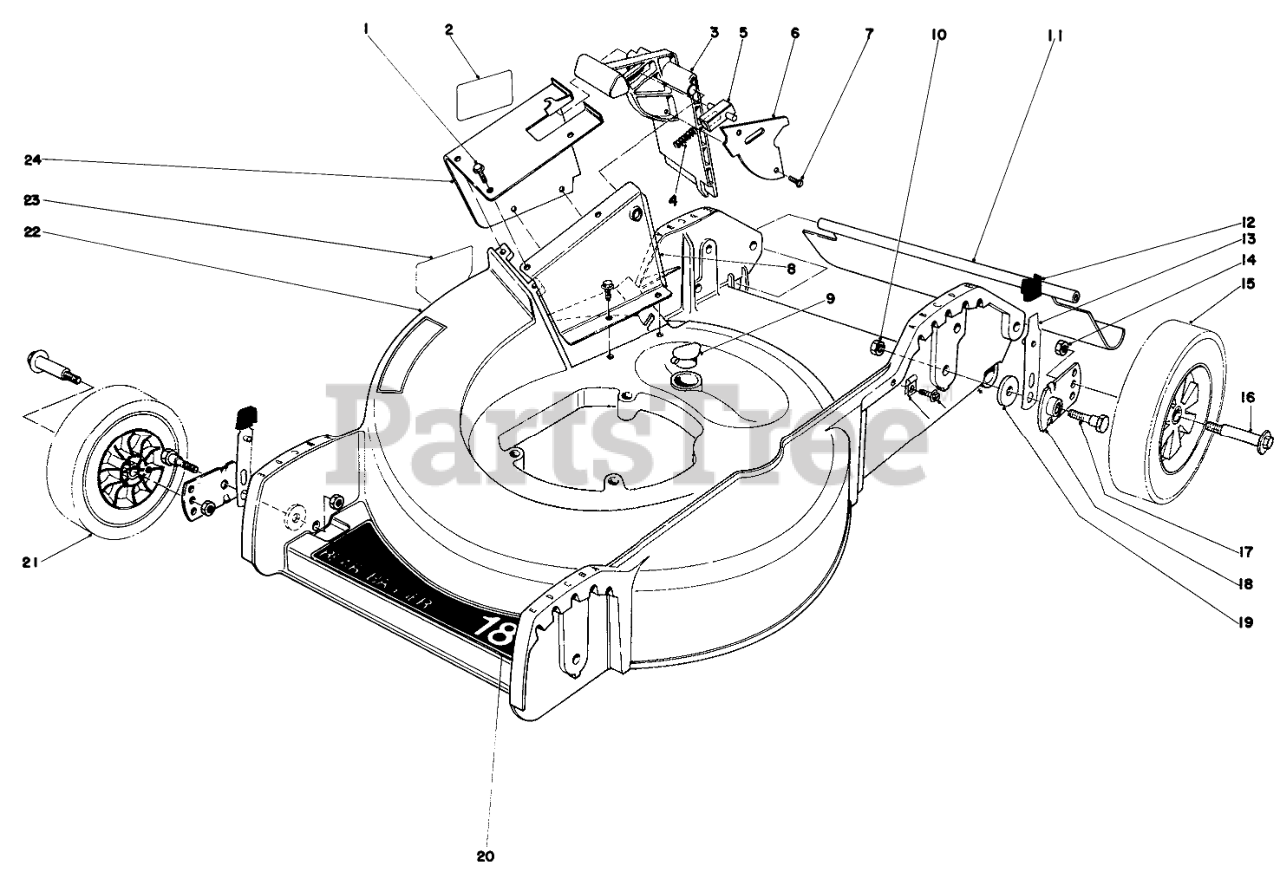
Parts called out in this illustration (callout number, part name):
1	SCREW
2	Decal Door
3	Door Mulching
4	SPRING-COMPRESSION, LATCH
5	Door Latch
6	Cover Door
8	Inner Tunnel
9	WASHOUT PLUG
10	Nut
11	SHIELD - TRAILING
12	KNOB-ARM
13	SPRING ARM ASM
14	Nut
15	WHEEL & TIRE ASM
16	BOLT-WHEEL
17	PIVOT SCREW
18	PIVOT ARM ASSY
19	PIVOT WASHER
20	Decal-Rear Bagger
21	Wheel & Tire Assembly
22	Housing
23	DECAL-DANGER
24	Tunnel Outer
